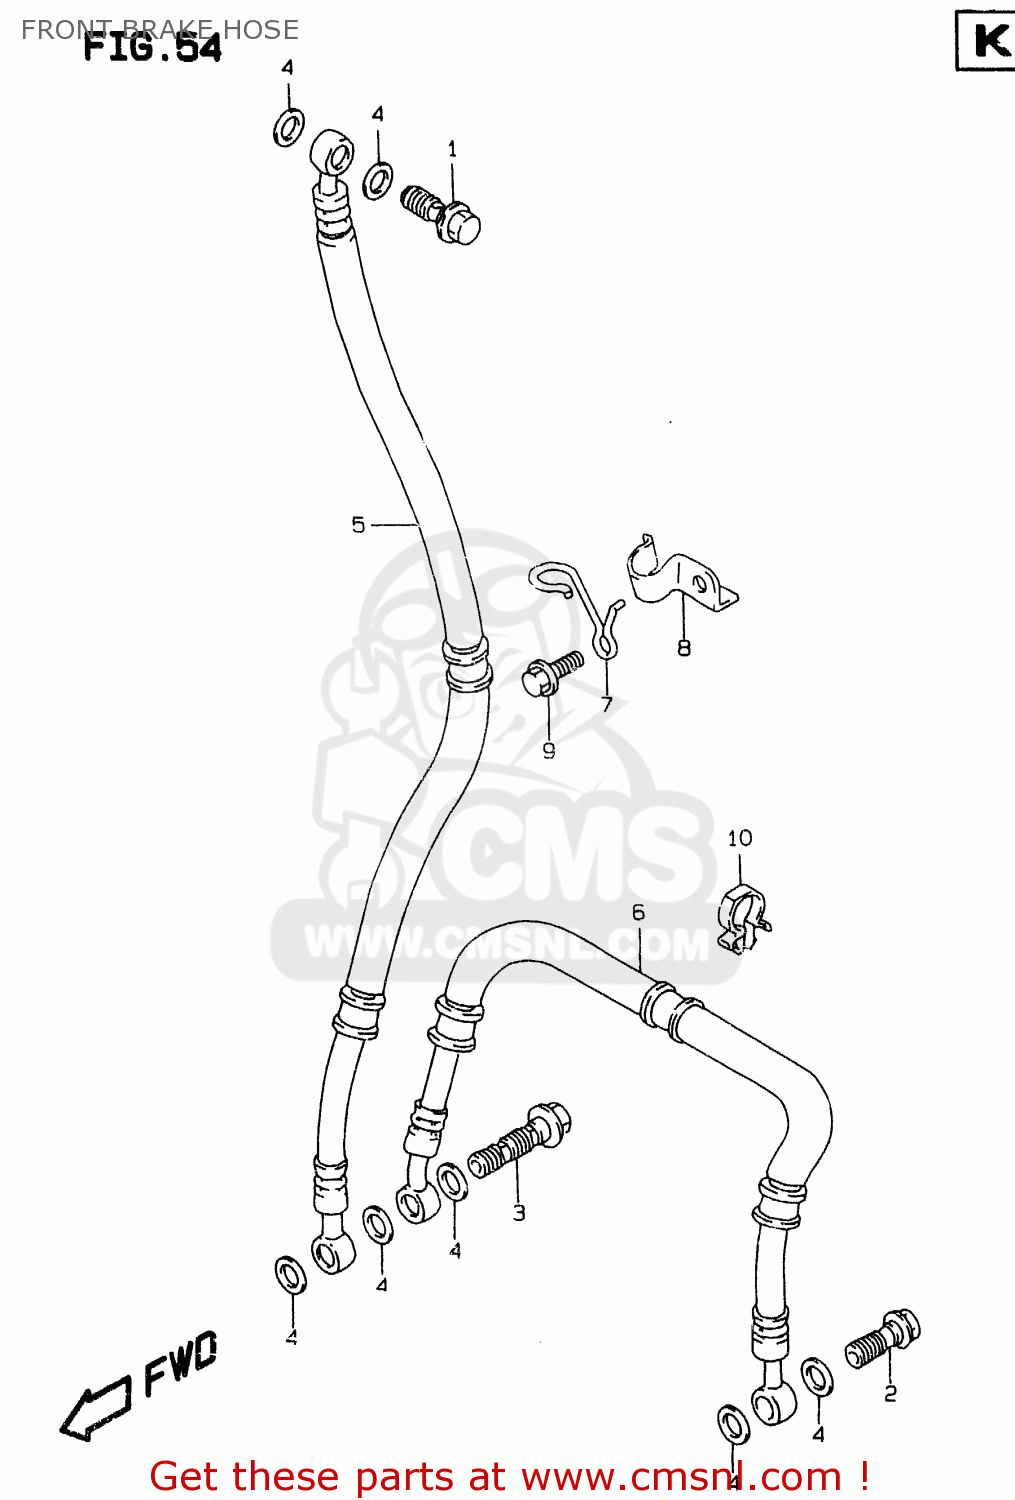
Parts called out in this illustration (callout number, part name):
1	BOLT UNION
2	BOLT UNION
3	BOLT UNION
4	WASHER(10X15X1.5)
5	HOSE,FR BRAKE NO.1
6	HOSE,FR BRAKE NO.2
7	GUIDE,FRONT BRAKE HOSE
8	CLAMP,FR BRAKE HOSE UPR
9	BOLT
10	CLAMP
